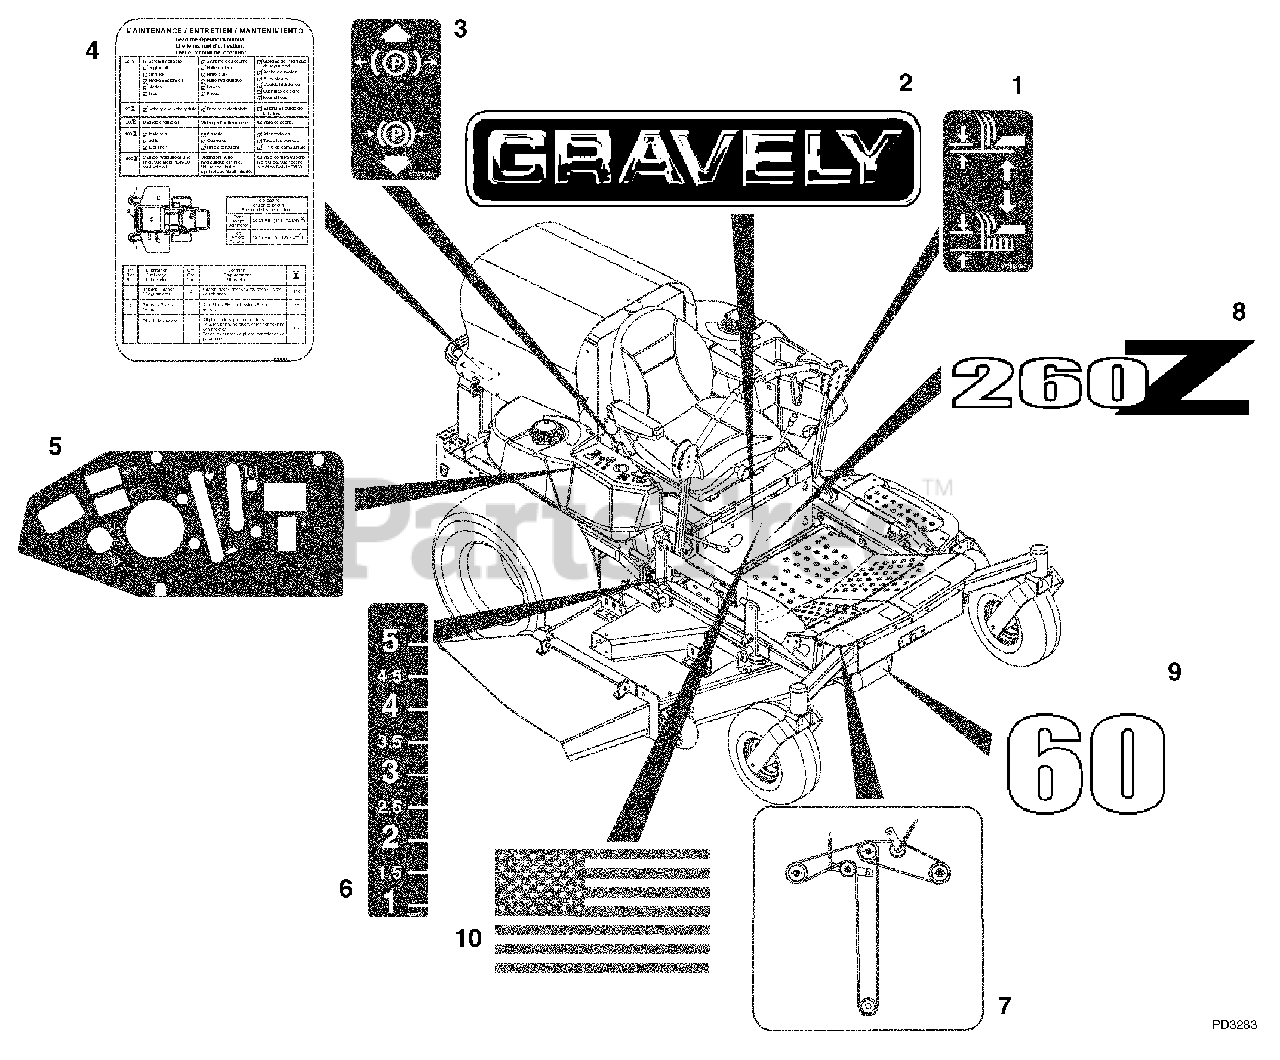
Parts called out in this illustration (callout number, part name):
1	Decal, Lift Lever
2	Decal, 15" Gravely Logo
3	Decal, Parking Brake Lever
4	Decal, Service Instructions
5	Decal, Gas Control Panel (036, 038, 309)
5	Decal, Diesel Control Panel (037, 039)
6	Decal, Height of Cut
7	Decal, Belt Diagram (036, 038, 309)
7	Decal, Belt Diagram (037, 039)
8	Decal, PM-260Z (036, 038, 309)
8	Decal, PM-272Z (037, 039)
9	Decal, 60 (036, 038, 309)
9	Decal, 72 (037, 039)
10	Decal, American Flag
